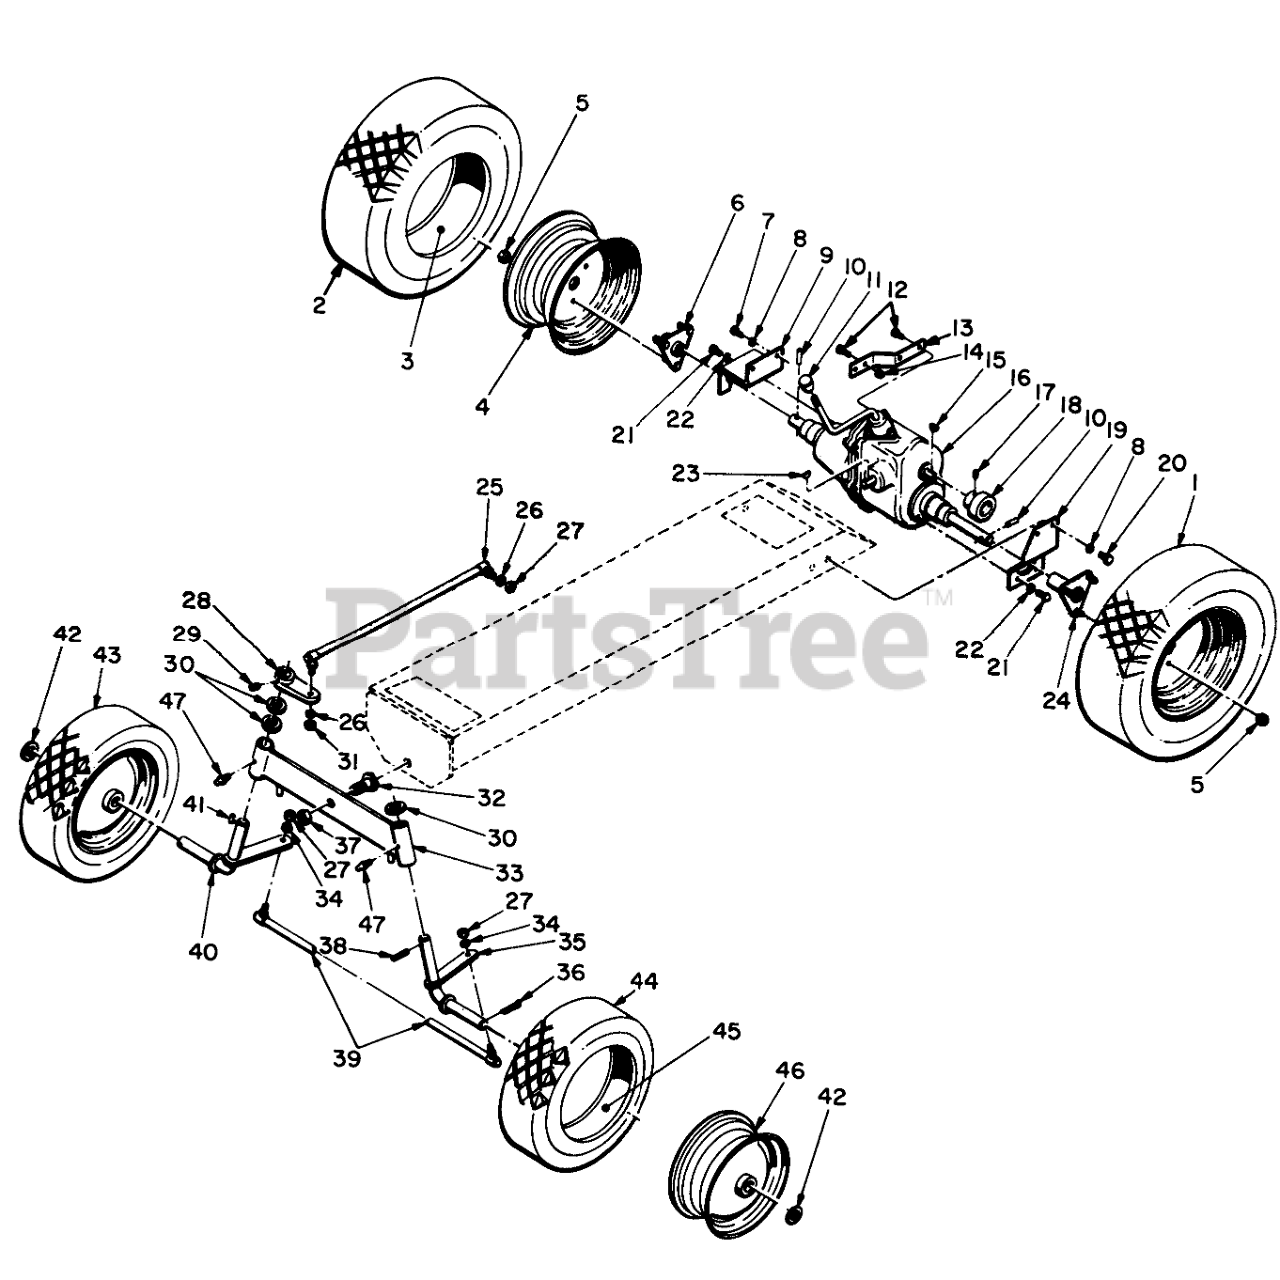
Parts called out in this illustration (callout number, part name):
1	Rear Wheel Assy
2	Terra Tire, 6.50 x 8, 16-in. dia.
3	VALVE -STEM
5	LUG NUT
6	Wheel Hub, RH
7	SCREW-HH
8	WASHER-LOCK
9	Axle Support, RH
10	PIN-ROLL, SLOTTED
11	Knob
12	SCREW-HH
13	Transmission Bracket
15	Woodruff Key
16	Transmission (transaxle)
17	SCREW-SET
18	Brake Drum
19	Axle Support, LH
20	SCREW-HH
21	SCREW-HH
22	WASHER-LOCK
23	KEY-WOODRUFF
24	Wheel Hub, LH
25	Steering Rod
26	WASHER-LOCK
27	NUT-HEX
28	Steering Lever
29	SCREW-SQH
30	WASHER-FLAT
31	NUT-HJ
32	Leveler Head Bolt
33	Wheel Support
34	WASHER-LOCK
35	Axle Assy, LH
36	PIN-COTTER
37	Nut
38	Roll Pin
39	Tie Rod
40	Axle Assy, RH
41	KEY-WOODRUFF
42	Washer
43	Wheel Assy.
44	Tire
47	Grease Fitting
